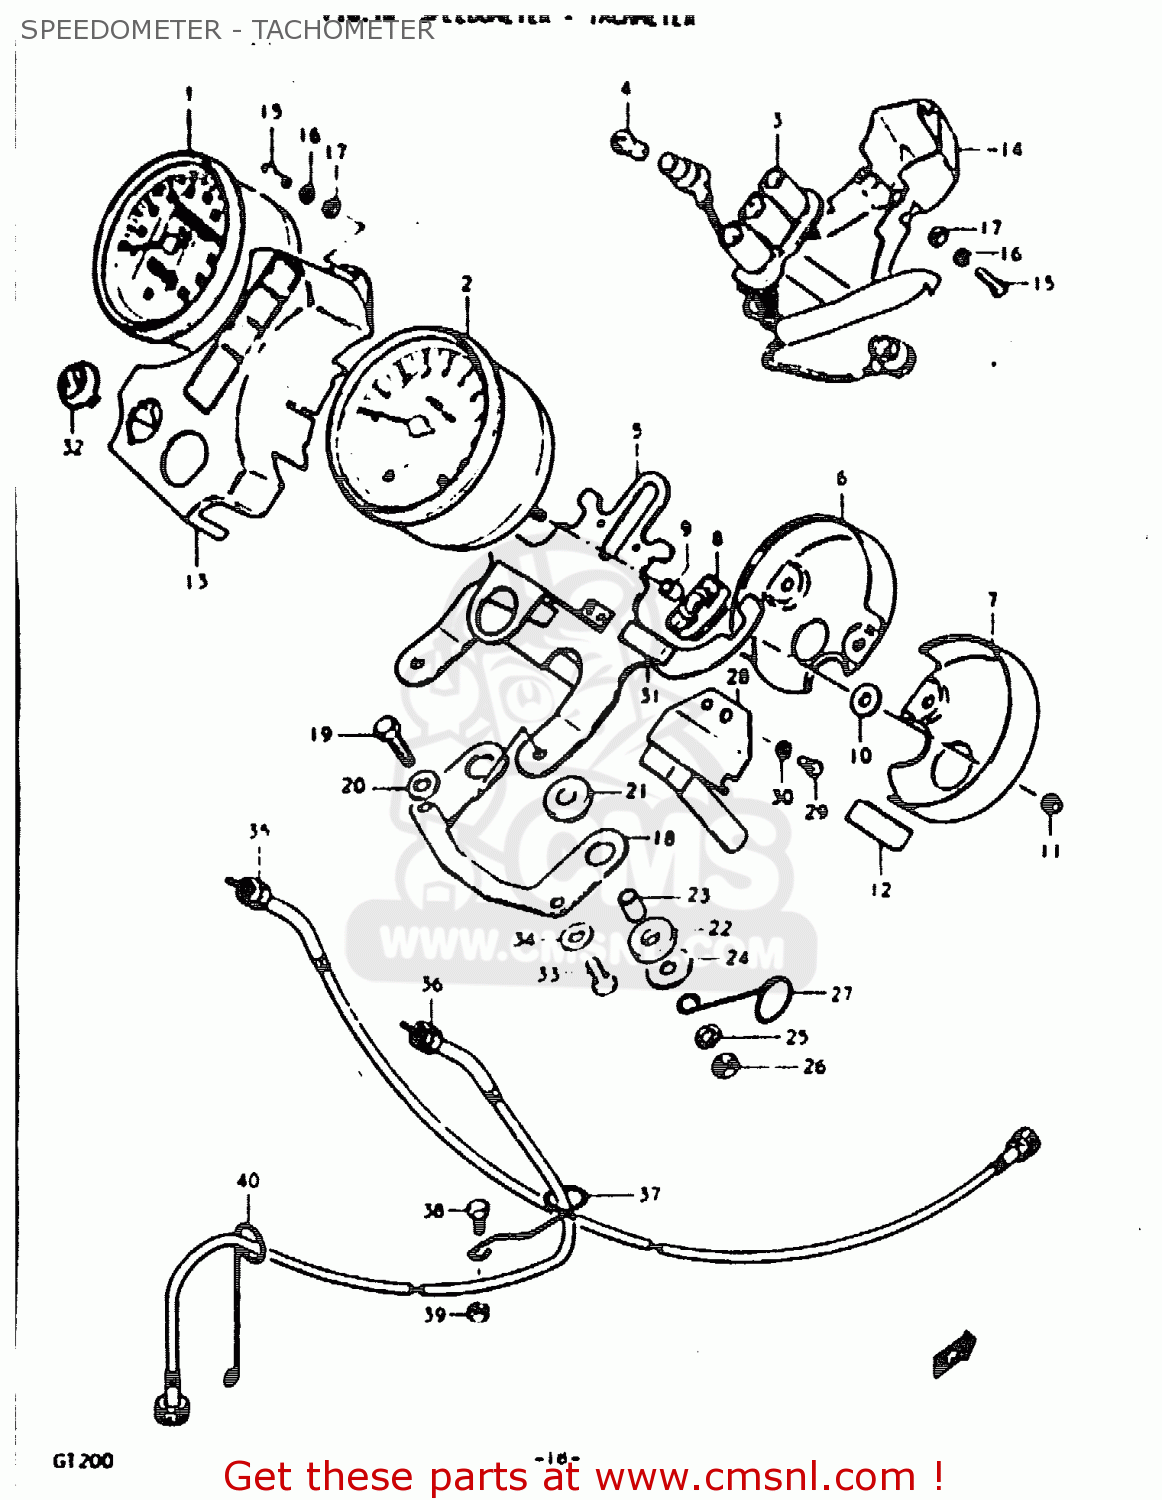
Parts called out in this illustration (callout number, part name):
1	SPEEDOMETER ASSY
2	TACHOMETER ASSY
3	SOCKET
4	BULB(12V3.4W,STANLEY,A72A)
5	BRACKET
6	UNDER COVER,SPEEDOMETER
7	UNDER COVER,TACHOMETER
8	CUSHION,METER
9	SPACER
10	WASHER (5.5X16X1.2)
11	NUT
12	CUSHION,METER
13	CASE, PILOT BULB
14	COVER
15	SCREW(4X16)
16	WASHER,PILOT UNDER CASE
17	WASHER
18	BRACKET
19	BOLT
20	WASHER
21	CUSHION
22	CUSHION
23	SPACER
24	WASHER (6.5X24X1.6)
25	LOCK WASHER
26	NUT
27	CLIP,TACHOMETER CABLE
28	HOLDER,COUPLER
29	SCREW
30	LOCK WASHER
31	PAD
32	CAP,SPEED WARNER LAMP HOLE
33	BOLT, UPPER
34	WASHER
35	CABLE ASSY, SPEEDOMETER
36	CABLE ASSY, TACHOMETER
37	GUIDE, TACHOMETER CABLE
38	BOLT
39	NUT
40	GUIDE, TACHOMETER CABLE
